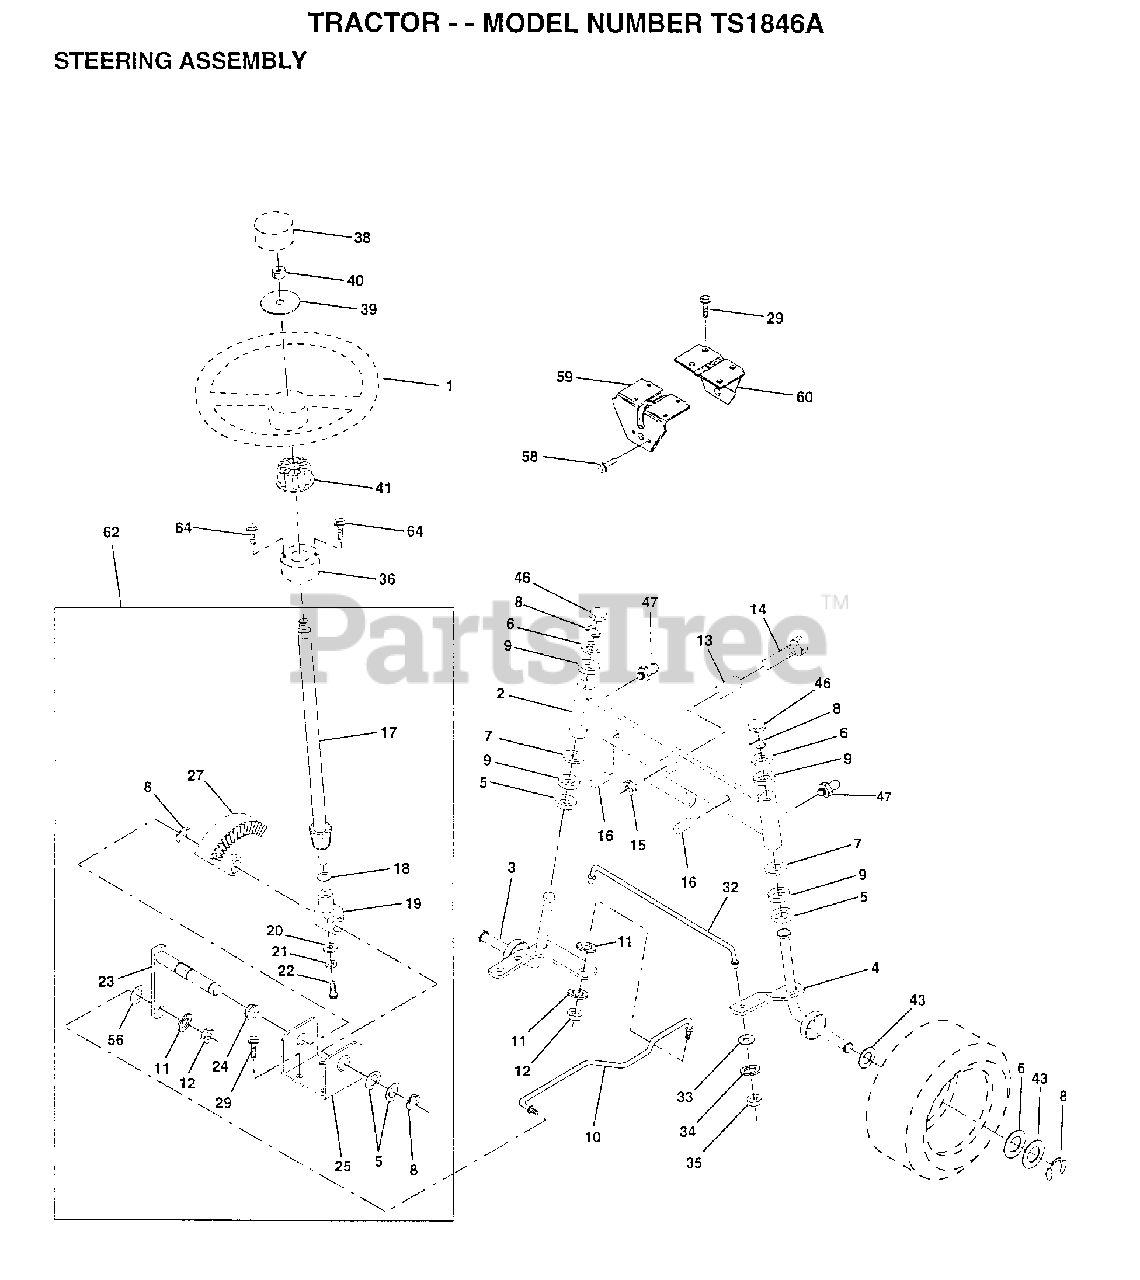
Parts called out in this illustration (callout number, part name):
2	AXLE ASM FRONT
3	SPINDLE LH
4	SPINDLE RH
5	WASHER .T
6	WASHER
7	WASHER
8	RING
9	COL. SRTG. BEAR.
11	LOCKWASHER
13	BEARING
14	BOLT LT
15	"NUT-LOC,FLANGE LT"
16	AXLE PIN
18	THRUST WASHER
19	SUPPORT.SHAFT
21	LOCKWASHER
22	SCREW.SCKTHD.CAP
24	NYLINER T
25	"BRKT,STEERING"
27	GEAR SECTOR
29	SCREW
32	TIE ROD
33	WASHER M
34	LOCKWASHER
35	NUT.LOCK.5/16-24
36	BUSHING.STRG.3/4
38	"INSERT,STR WHEEL"
39	WASHER
41	ADAPTER LT
43	WASHER
46	CAP
47	ZERK M
56	WASHER
58	SCREW LT
59	SUPPORT-SADDL T
60	SUPPORT.SADDLE.FT
62	KIT.STEER.20.31
64	"SCREW-TT,10-32 FL"
